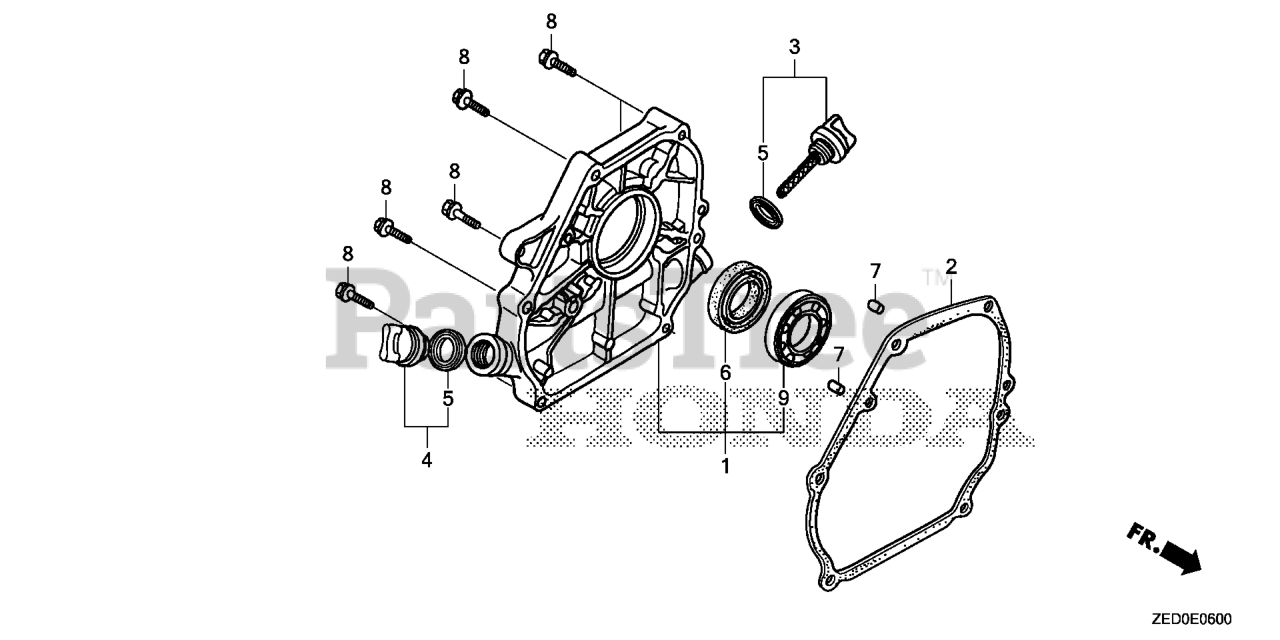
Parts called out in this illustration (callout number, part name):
1	COVER ASSY., CRANKCASE
2	GASKET, CASE COVER (NON-ASBESTOS)
2	GASKET, CASE COVER (NINGBO SIL GASKET)
3	CAP ASSY., OIL FILLER
4	CAP ASSY., OIL FILLER
5	GASKET, OIL FILLER CAP
6	OIL SEAL (25X41X6)
6	OIL SEAL (25X41X6) (ARAI) (NOT AVAILABLE)
7	PIN A, DOWEL (8X14)
8	BOLT, FLANGE (8X32)
9	BEARING, RADIAL BALL (6205)
